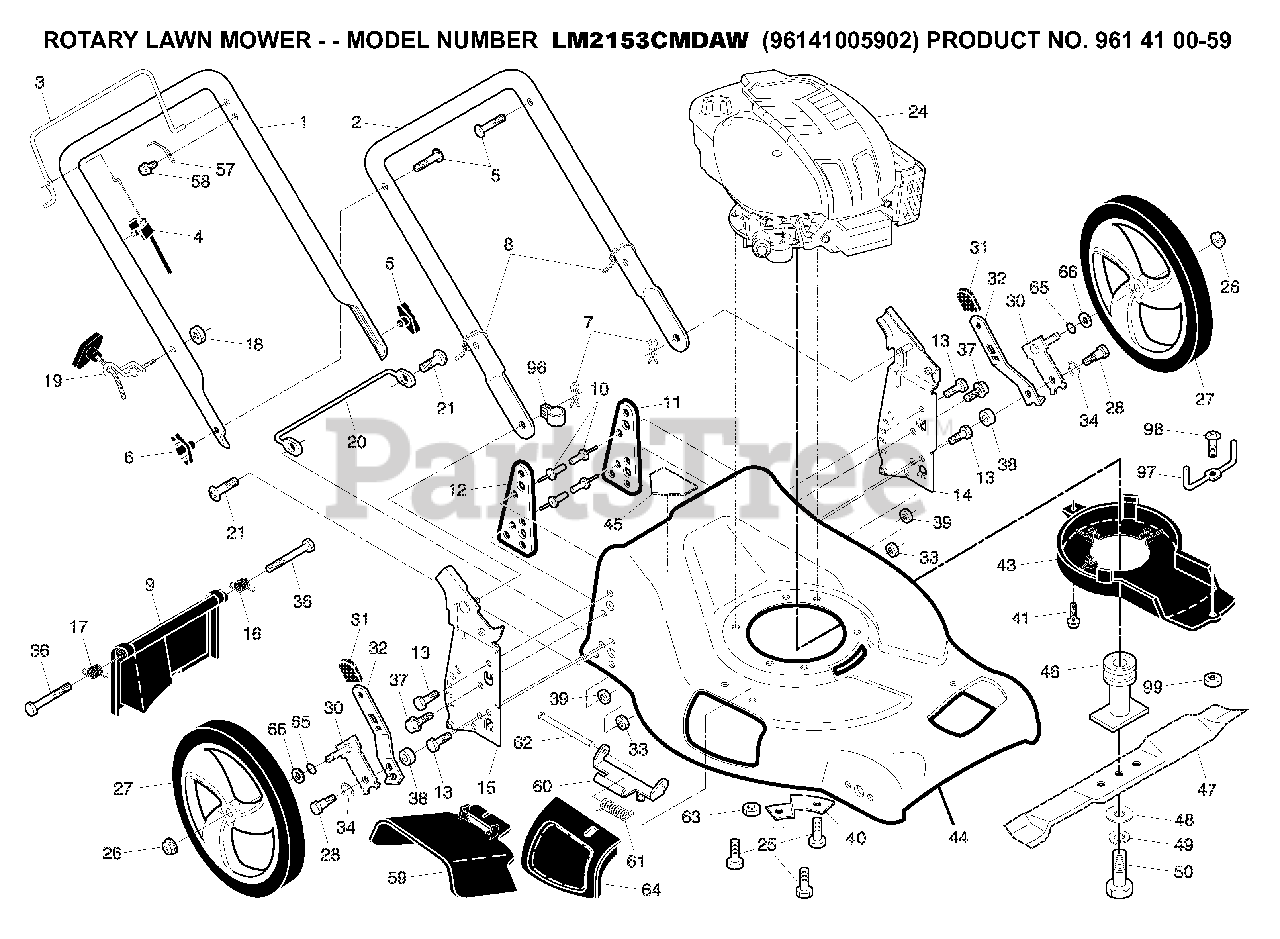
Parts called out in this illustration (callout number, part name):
1	HANDLE.UPER.D.ST.EZ
2	LOWER HANDLE
4	CABLE.MZR
5	BOLT, HANDLE 5/16-18X1.75
6	KNOB, DEFLECTOR
7	HAIRPIN COTTER
8	TIE GUIDE
9	REAR DOOR ASSEMBLY
10	RIVET BLIND
13	SCREW 14-20 X 5/8
14	BRKT.ASM.HNDL.21FGD
15	BRKT.ASM.HNDL.21FGD.EZ
16	SPRING.REAR.DOOR.EZ.21.LT
17	SPRING.REAR.DOOR.EZ.21.RT
18	NUT
19	GUIDE.ROPE.STD.BLK.ZIN
21	SCREW
25	BOLT 3/8-16X1-1/8
26	NUT.HEX.FLANGE.3/8-16.LOCKNUT
28	SHOULDER BOLT 5/16-18
30	ARM.ASM.AXLE.REAR.5/9.POS.BZP
31	SELECTOR KNOB
32	SELECTOR SPRING
33	NUT.71038.31-18.HEX.NYLOCK
34	WASHER FLAT
37	BOLT
38	SPACER.HEIGHT.ADJUSTER
39	NUT, HEX FLANGE 5/16-18
40	BRACKET
41	SCREW.HEX.WSH
43	DEBRIS SHIELD
45	DECAL.INTERNATIONL.CUTFINGER
47	BLADE.21.PUSH
48	WASHER,HARDEN
49	LOCKWASHER
50	SCREW, HEX HD 3/8-24 X 1-3/8
57	BRACKET UPSTOP
59	DISCHARGE DEFLECTOR
60	HINGE BRACKET ASSEMBLY
61	SPRING.TORSION
62	ROD.HINGE.21
63	LOCKNUT
64	DOOR.MULCH.21.REAR
65	O-RING..070X.487.NEOPRENE
66	WASHER PM
96	CLIP.CABLE.BLK
97	KEEPER.BELT.FGD
99	NUT.HEX.#8
